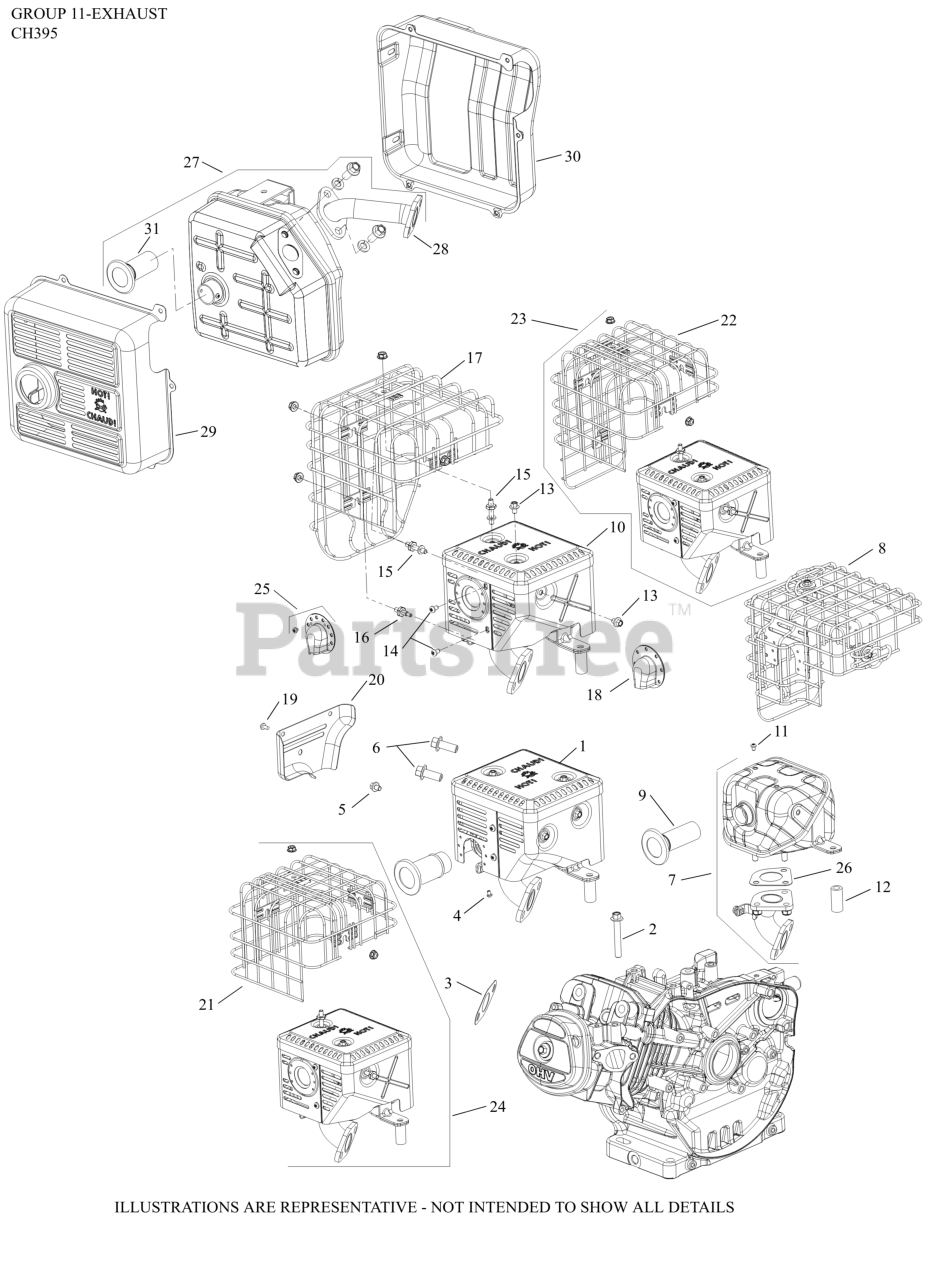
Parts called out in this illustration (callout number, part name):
2	SCREW, M8 X 55
3	GASKET, MUFFLER
6	SCREW, M10 X 25
9	ARRESTOR ASSEMBLY, SPARK
10	MUFFLER ASSEMBLY W/HEAT SHIELD
12	POST, MUFFLER BRACKET
14	SCREW, M5 X 8
26	GASKET, MUFFLER
